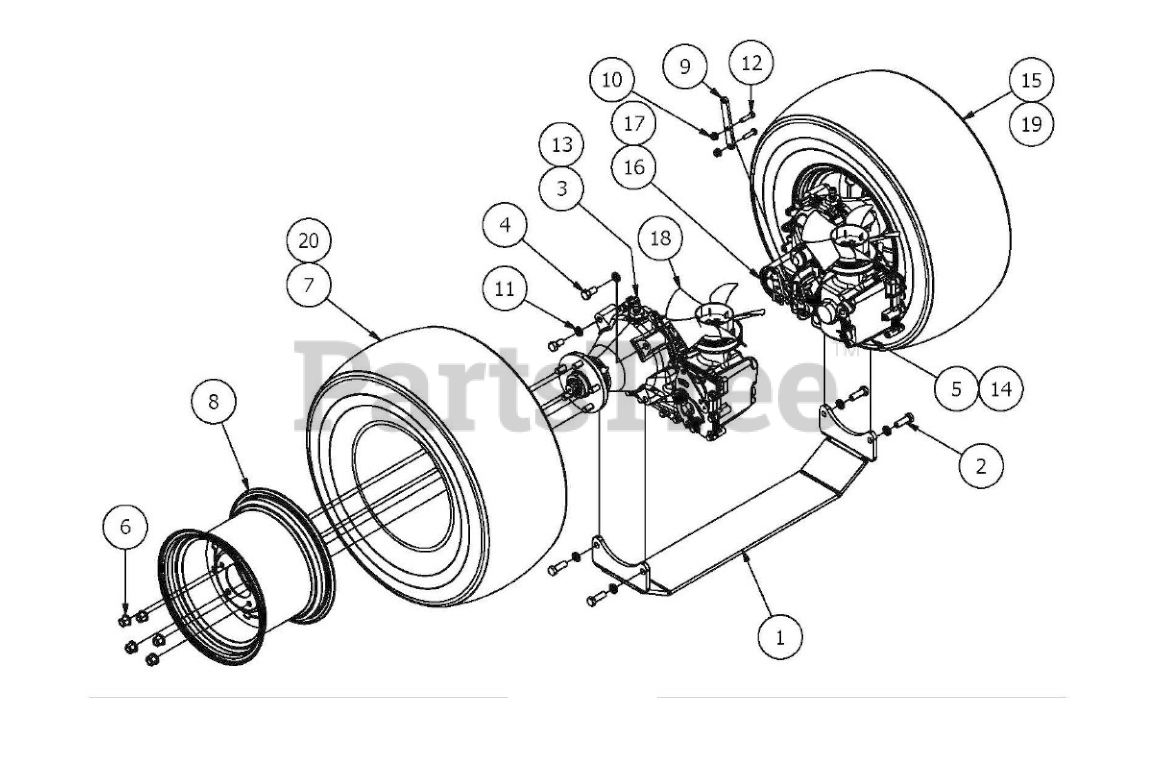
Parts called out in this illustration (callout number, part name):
1	Outlaw Transaxle Cross Brace
2	1/2" x 1 1/2" Hex Bolt
3	ZT-5400 Left
4	1/2" x 1" Hex Bolt
5	ZT-5400 - Right
6	Acorn Lug Nut
7	24 x 12 12 Tire Pro Maxxis
8	12x12" Black Wheel For 2015 Outlaw
9	2015 Outlaw Brake Adapter (4400 Transaxles Only)
10	5/16" Flange Nut Zinc W/Serrations (4400 Transaxles Only)
11	1/2" Lock Washer
12	5/16 x 1 1/4 Hex Bolt
13	4400 Transaxle - Left (Base Outlaw)
14	4400 Transaxle - Right (Base Outlaw)
15	24 x 12.00 - 10 Tire and Black Wheel Assembly
16	Hydro Filter for Outlaw Extreme
17	4400 Hydro Filter for Outlaw
18	Fan/Pulley Kit for Oulaw
19	2017 Outlaw Reaper Turf Wheel and Tire Assembly 24x12-12
20	2017 Outlaw 24x12-12 Reaper Tire
